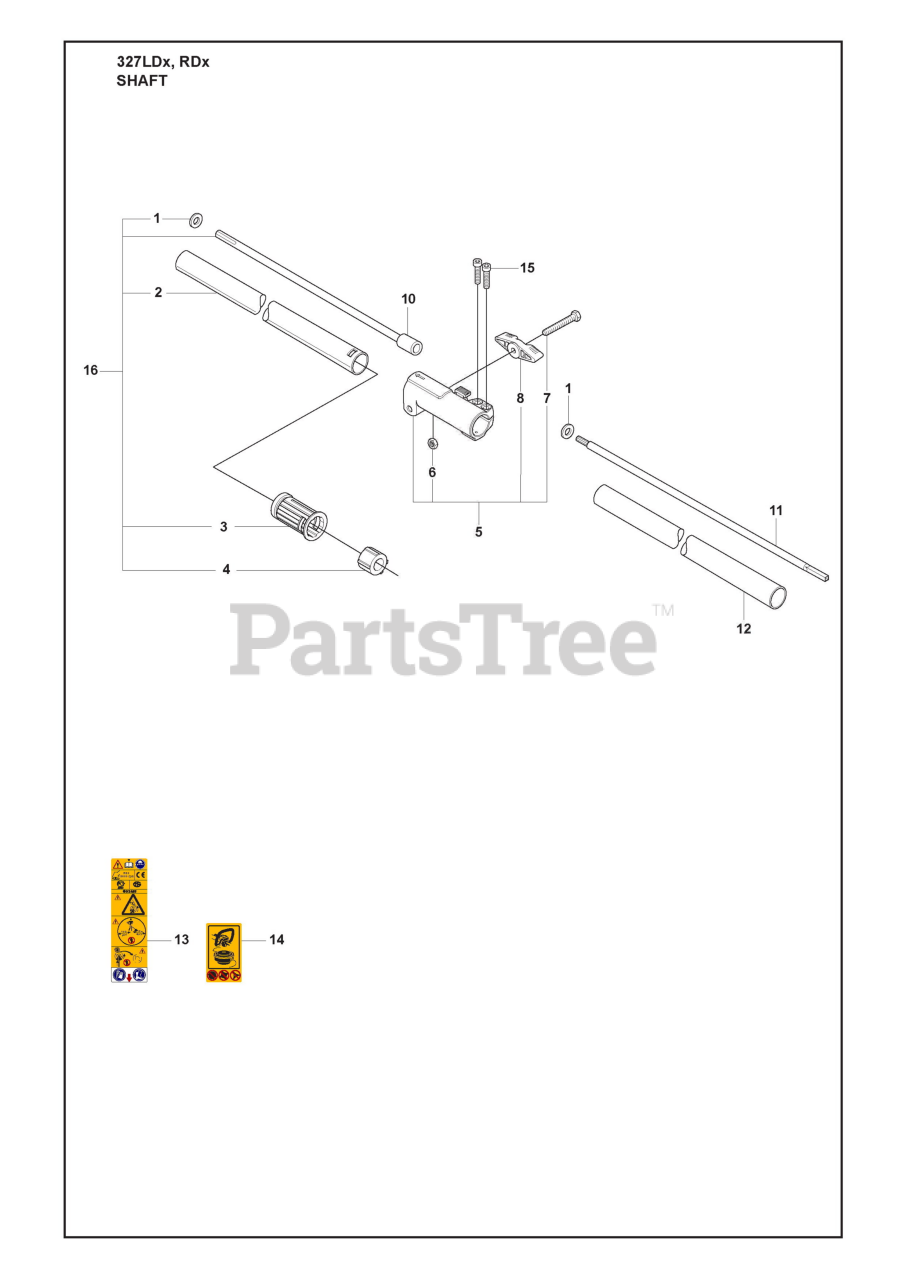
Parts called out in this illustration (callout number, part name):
2	TUBE
3	PLUG
4	BUSHING
5	CLAMPING SLEEVE
7	BOLT FLANGE
10	SHAFT LOWER
11	SHAFT
12	TUBE
13	RP WARNING DECAL
14	DECAL WARNING "NO BLADES"
14	ANTIVIBRATION ELEMENT
16	TUBE
